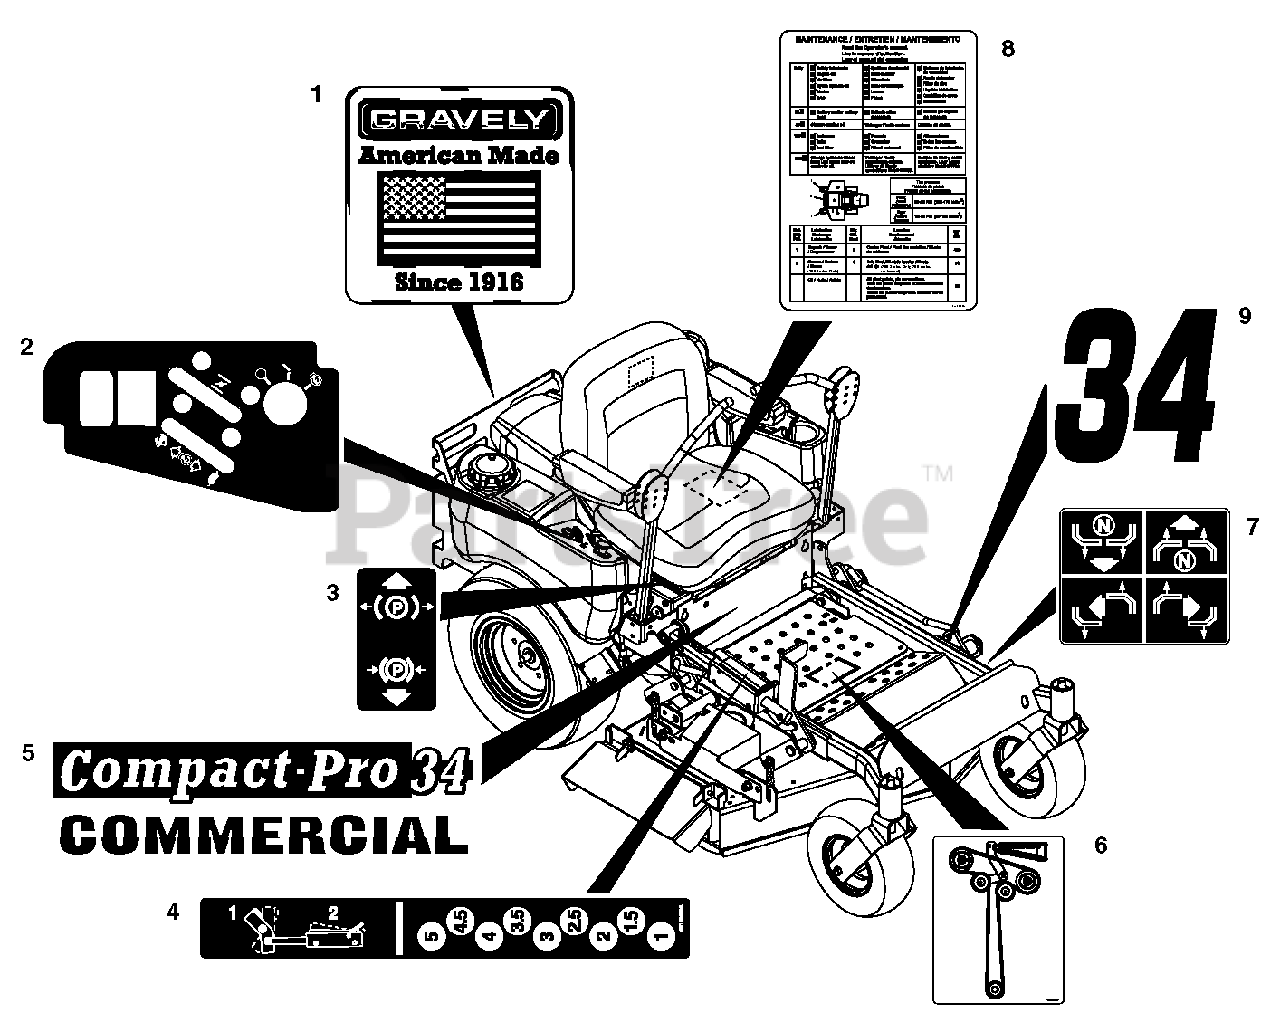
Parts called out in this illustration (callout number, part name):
1	Decal, Gravely American Made
2	Decal, Control Panel
3	Decal, Parking Brake Lever
4	Decal, Height of Cut
5	Decal, Compact-Pro 34
6	Decal, Belt Diagram
7	Decal, Instructional Steering
8	Decal, Maintenance Instructions
9	Decal, 34Z
